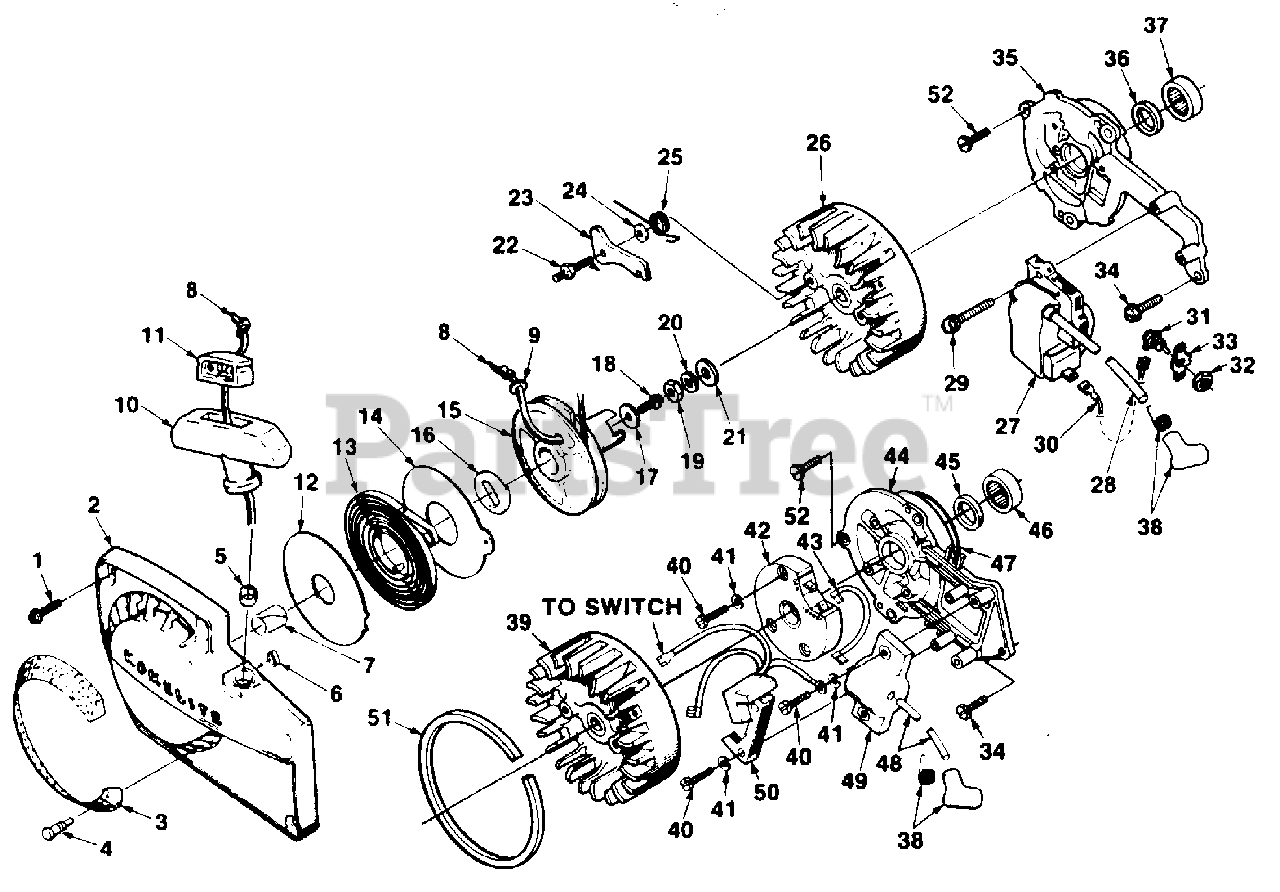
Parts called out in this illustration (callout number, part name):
1	SCREW- Hex hd. 12-24 x 5/8
2	HOUSING- Fan
3	SCREEN- Fan housing
4	STUD- Drive
5	BUSHING- Starter rope
6	BUSHING- Starter post
7	BUSHING- Rewind spring
8	ROPE- Starting
10	GRIP- Starting rope
11	INSERT- Rope retaining
12	SHIELD- Spring (inner)
13	SPRING- Rewind
14	SHIELD- Spring (outer)
15	PULLEY- Rewind starter
16	LOCK- Rewind spring
17	WASHER- Retaining
18	SCREW- Hex hd. 10-32 x 1/2
19	NUT- Hex 3/8-24
20	WASHER- Lock 3/8
21	WASHER- Flat 3/8
22	STUD- Pawl
23	PAWL- Starter
24	WASHER- Lock #12
25	SPRING- Starter pawl
26	ROTOR- Magneto
27	MODULE- Ignition
28	LEAD- High tension
29	SCREW- Sems hex hd.
30	LEAD- Ground
31	SWITCH- Toggle
32	NUT
33	PLATE- Indicating
34	SCREW- 1/4-20
35	PLATE- Back
36	SEAL
37	BEARING
38	TERMINAL- Spark plug
39	ROTOR- Magneto (prior to lot #C-246)
40	SCREW- Pan 8-32 x 3/4 (prior to lot #C-246)
41	WASHER- Lock #8 (prior to lot #C-246)
42	MODULE- Ignition (prior to lot #C-246)
43	LEAD- Transformer (prior to lot #C-246)
44	PLATE- Back (prior to lot #C-246)
45	SEAL
46	BEARING- Roller
47	"O" RING
48	LEAD- High tension (prior to lot #C-246)
49	COIL- Transformer (prior to lot #C-246)
50	COIL- Core and generator (prior to lot #C-246)
51	RING- Air flow (until lot #7045 only)
52	SCREW- Hex cap 1/4-20 x 5/8
